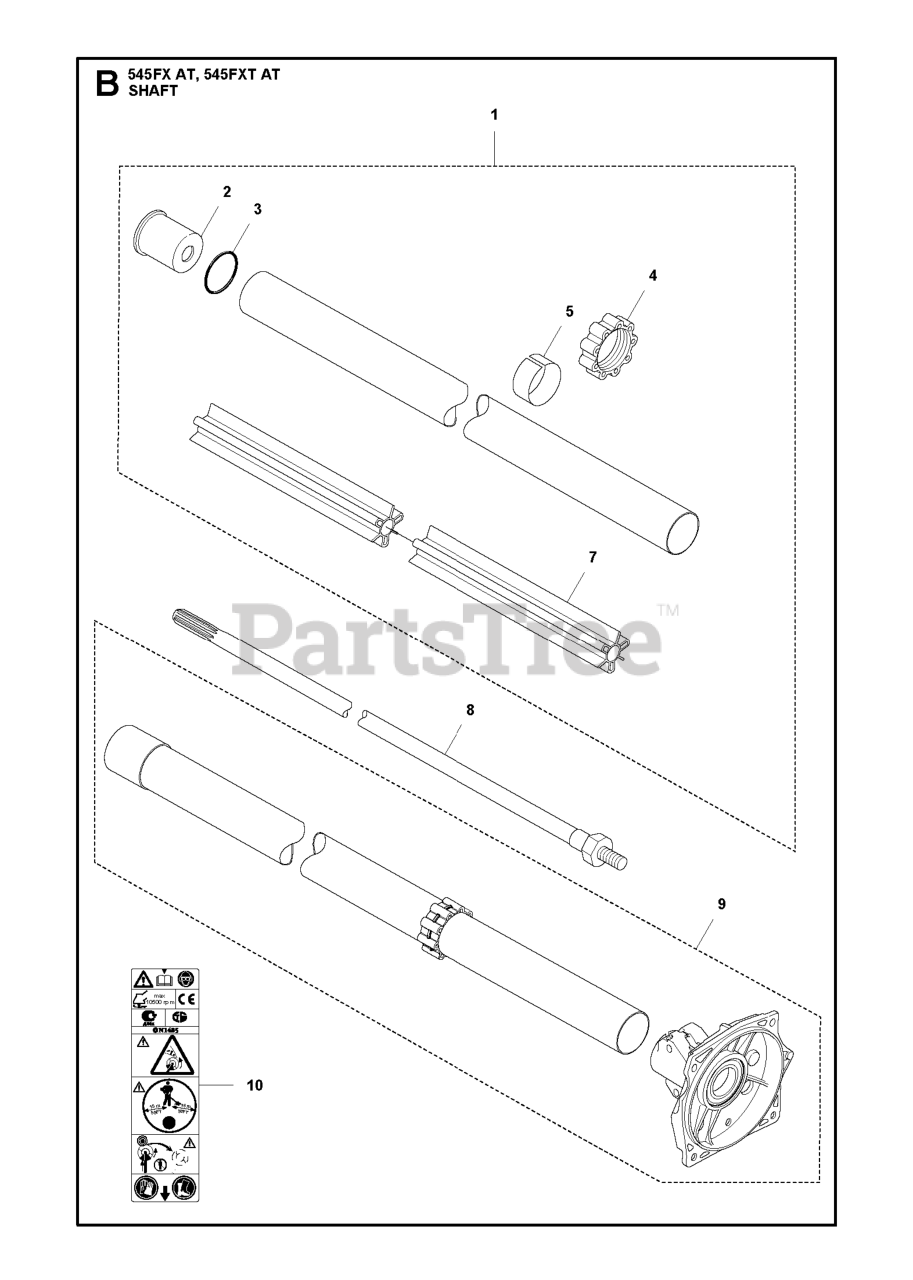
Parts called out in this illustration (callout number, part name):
1	Tubes
2	SPACER SLEEVE
4	MOVEMENT LIMITER
7	BEARING SHAFT
10	LABEL WARNING TRIMMERS AND BRU
